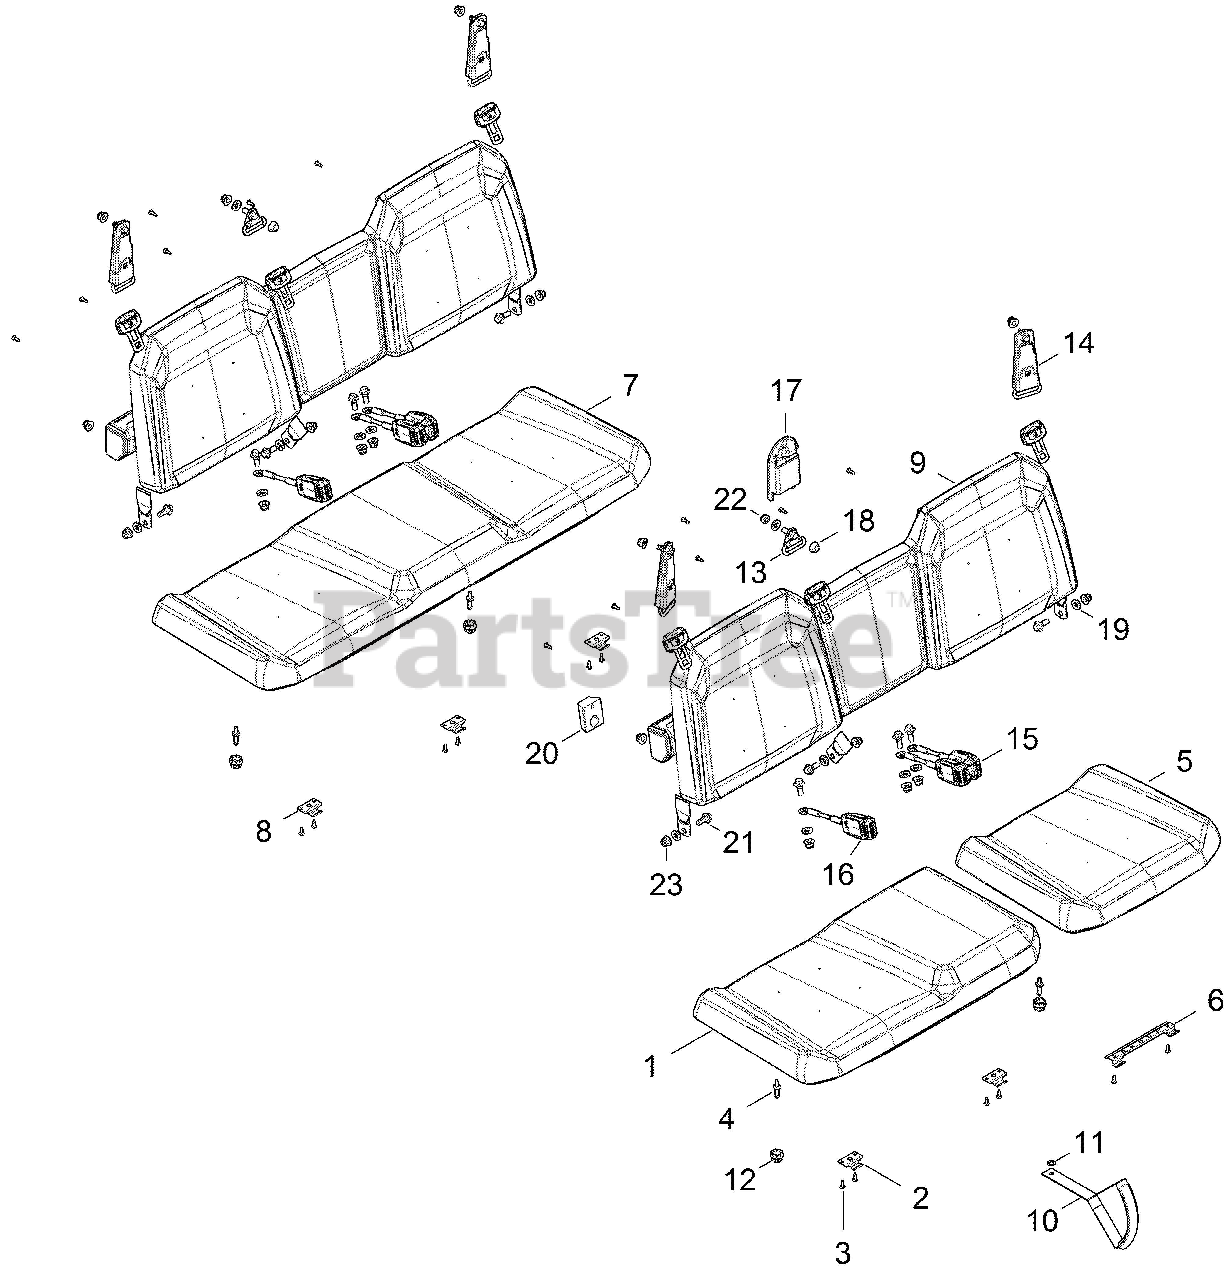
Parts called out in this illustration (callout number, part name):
1	ASM-SEAT,BTM,60,GRAVELY GRAY
2	BRKT-SEAT HINGE
3	SCR-TX TRUSS-#14X3/4,HI/LO ZBK
4	PIN-SEAT LATCH
5	ASM-SEAT,BTM,40,GRAVELY GRAY
6	BRKT-SEAT HINGE,DOUBLE
7	ASM.,SEAT,3 PASSENGER,BTM GRAY
8	BRKT-SEAT HINGE
9	ASM-SEAT,3PASS,BACK,GRVLY GRAY
10	STRAP, SEAT, CENTER
11	WASHER, NYLON
13	ASM-SEAT BELT,3PT,CENTER
14	ASM-SEAT BELT,3PT
15	BUCKLE-SEATBELT,9.6,DRIVER
16	BUCKLE-SEATBELT,9.6,PASSENGER
17	COVER-SEAT BELT MOUNT
18	CAP-BOLT HEAD
19	WASHER-SEATBELT,RUBBER
20	PAD-REAR,SEAT BASE
21	SCR-HXFLSH-M12X1.75-M14X9 ZOD
22	NUT-NYLOK,M12X1.5,0600110
23	NUT-HXFL M12X1.75 NYLOC ZOD
